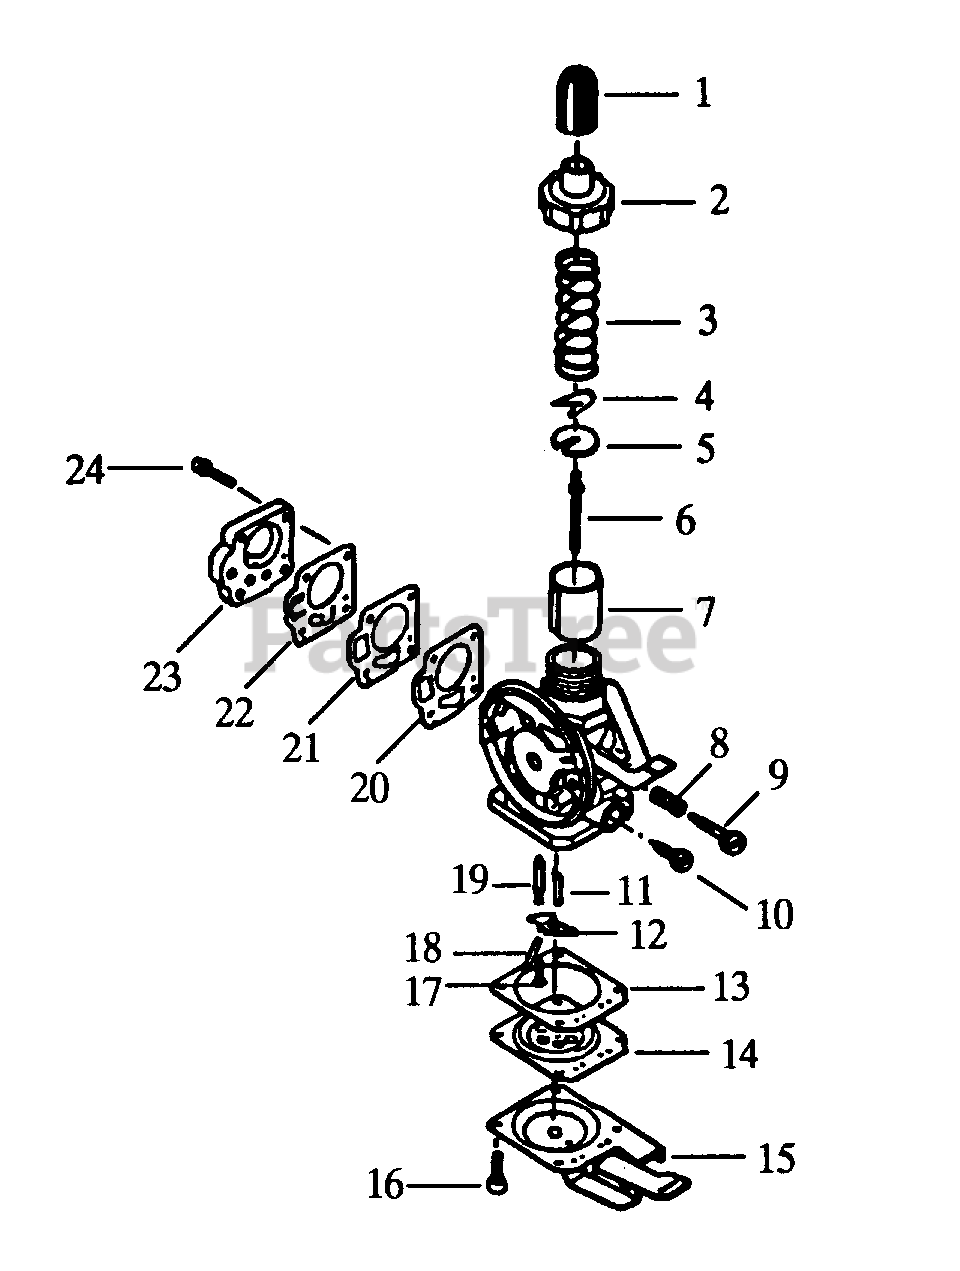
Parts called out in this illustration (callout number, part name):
5	Retainer
6	Jet Needle
7	Throttle Valve
10	Jet Needle
12	Arm Float
15	Diaphragm
16	Screw&Washer
18	Pin Float
19	Needle Valve
21	Check Valve
22	Diaphragm
23	Pump Cover
24	Screw & Washer
